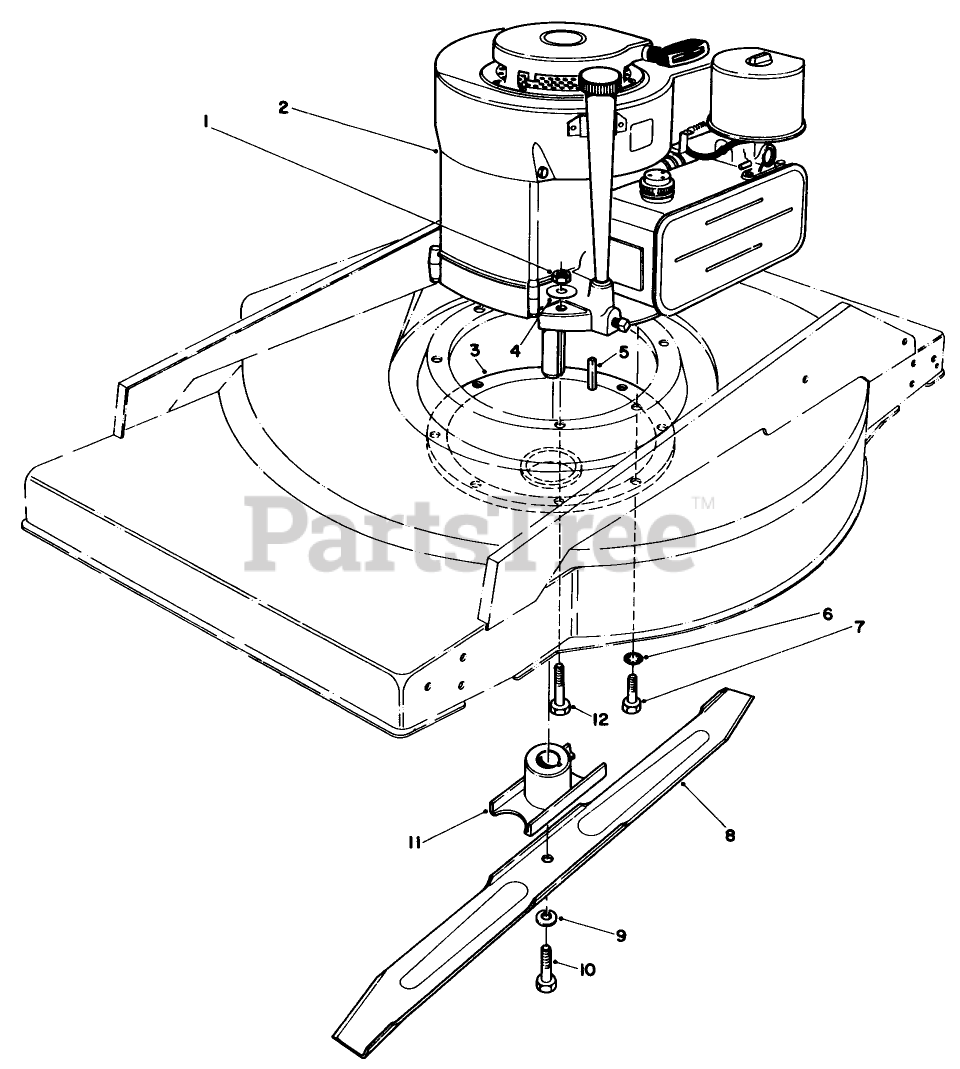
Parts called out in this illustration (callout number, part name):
1	NUT-LOCK, CONE
2	Engine
3	PROTECTOR-CRANKSHAFT
4	WASHER-FLAT
5	Key-Square
6	WASHER-LOCK, INTERNAL
7	SCREW-THD ROLL, HWH
9	WASHER-LOCK
10	BLADE SCREW
12	SCREW-HH
